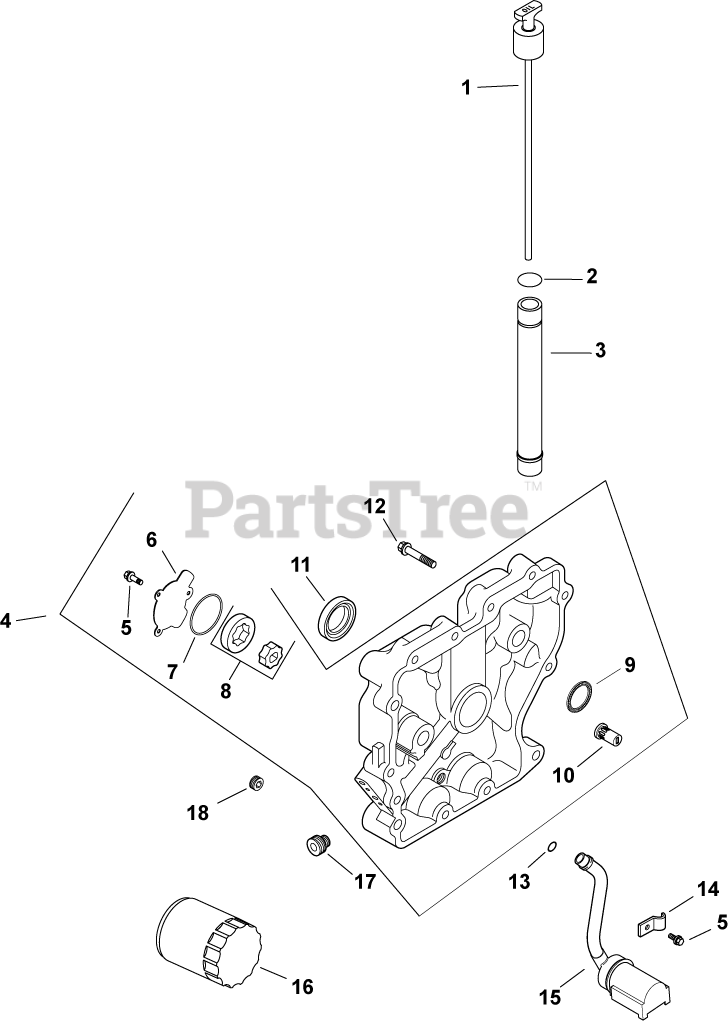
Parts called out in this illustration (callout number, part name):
1	KIT, OIL FILL TUBE - METAL
4	CLOSURE PLATE ASSEMBLY
5	SCREW,FLG THD FRM M5X0.8X16-(#25086398S)
6	COVER, OIL PUMP
7	O-RING (1.78" DIA)
8	PUMP ASSEMBLY, OIL
9	BEARING, CRANKSHAFT
10	VALVE, OIL PRESSURE RELIEF
11	SEAL, OIL
12	SCREW, FLG M8X1.25X45
13	O-RING (.5" DIA)
15	KIT, OIL PICK-UP
16	OIL FILTER
17	NIPPLE, OIL FILTER
18	PLUG, CTSK PIPE 1/8"
